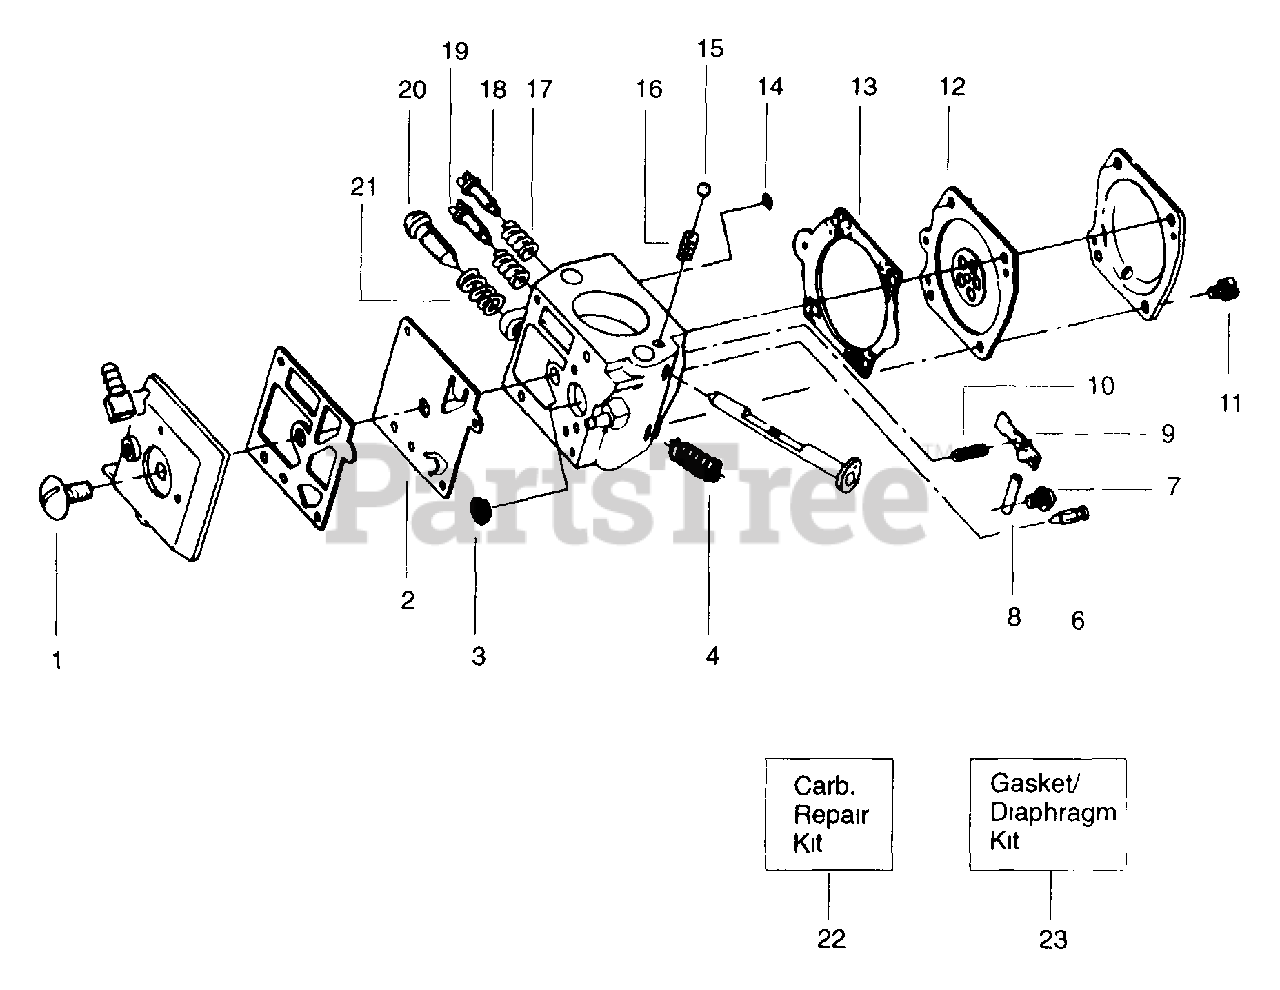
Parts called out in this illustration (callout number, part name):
2	Fuel Pump Diaphragm
3	Inlet Screen
4	Throttle Spring
6	Inlet Needle Valve
7	Screw
8	Pin
9	Metering Lever
10	Spring
12	Metering Diaphragm
13	Metering Diaphragm Gasket
14	Check Valve Screen
16	Spring
17	Needle Adjusting Spring
18	High Speed Needle
19	Idle Needle
20	Idle Adjust Screw
21	Idle Speed Spring
22	Carb Repair Kit
23	Gasket/Diaphragm Kit
